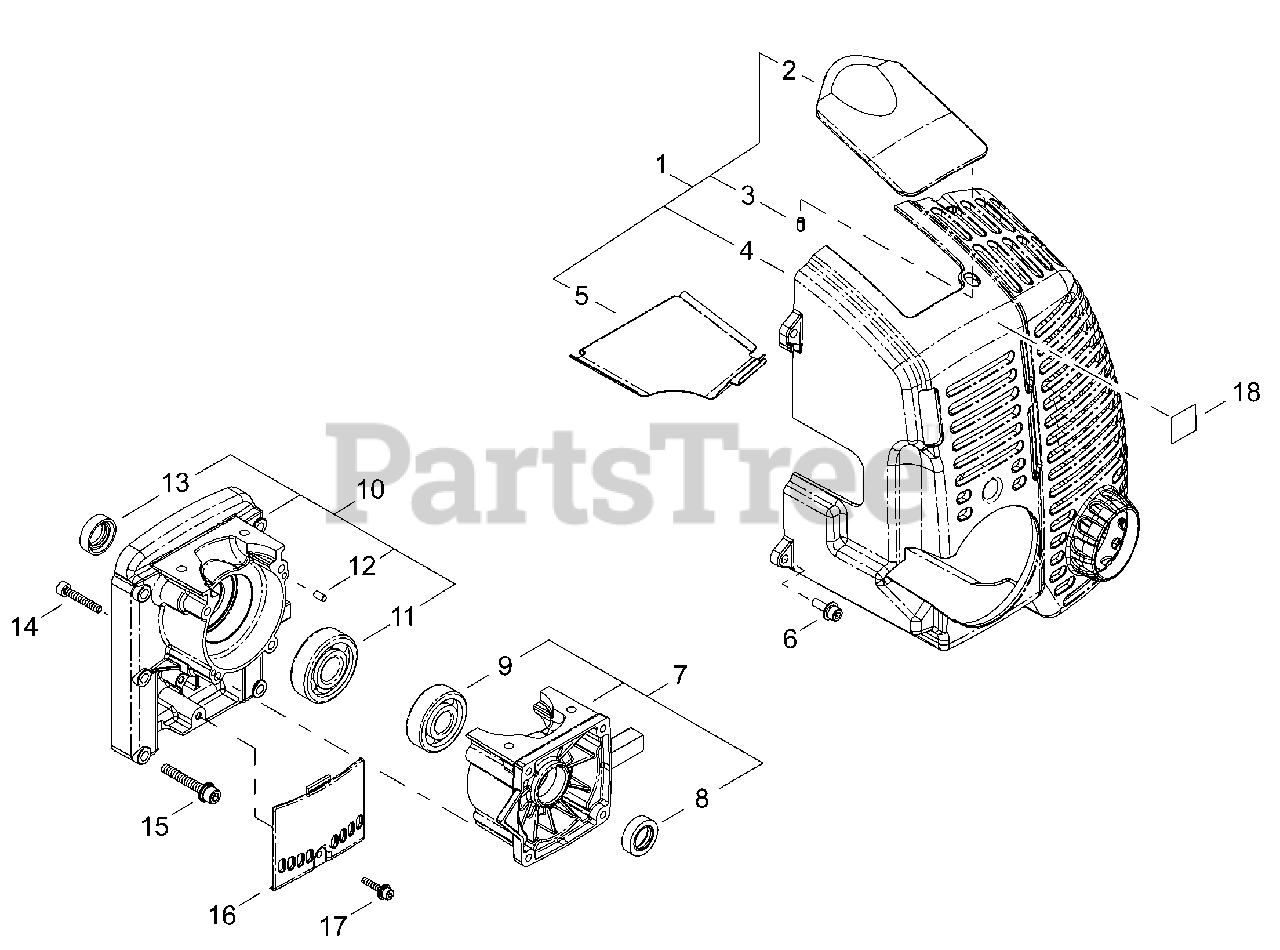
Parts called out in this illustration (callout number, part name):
1	COVER ASSY, ENGINE
2	COVER, SPARK PLUG
3	PIN, SPRING 4×8
4	COVER, ENGINE
5	HEAT SHIELD, EXHAUST
6	BOLT M5×16
7	CRANKCASE ASSY, S
8	SEAL, OIL 21
9	BEARING, BALL 6302 C3
10	CRANKCASE ASSY, M
11	BEARING, BALL 6303 C3
12	PIN, LOCATING Ø4×8
13	SEAL, OIL 21
14	BOLT 5×30
15	BOLT, ADHESIVE M6×40
16	COVER, DUST
17	BOLT M4×20
18	LABEL, CAUTION - HOT
